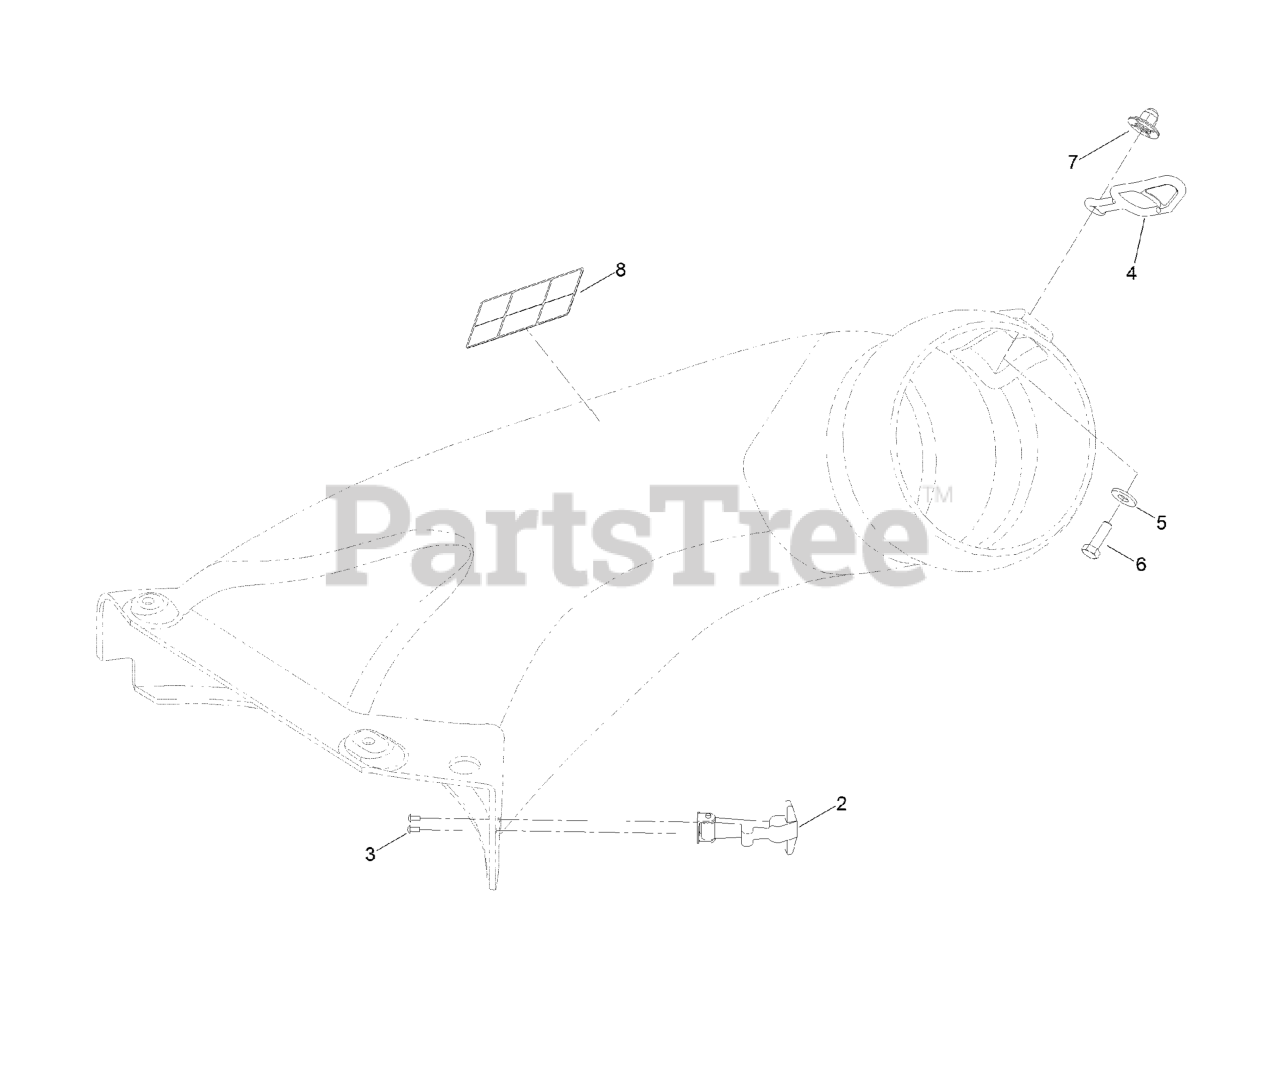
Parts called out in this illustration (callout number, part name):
2	HANDLE ASM
3	RIVET-POP
4	RETAINER-DUCT
5	WASHER-FLAT
6	SCREW-HH
7	NUT-IMPELLER
8	DECAL-DANGER
